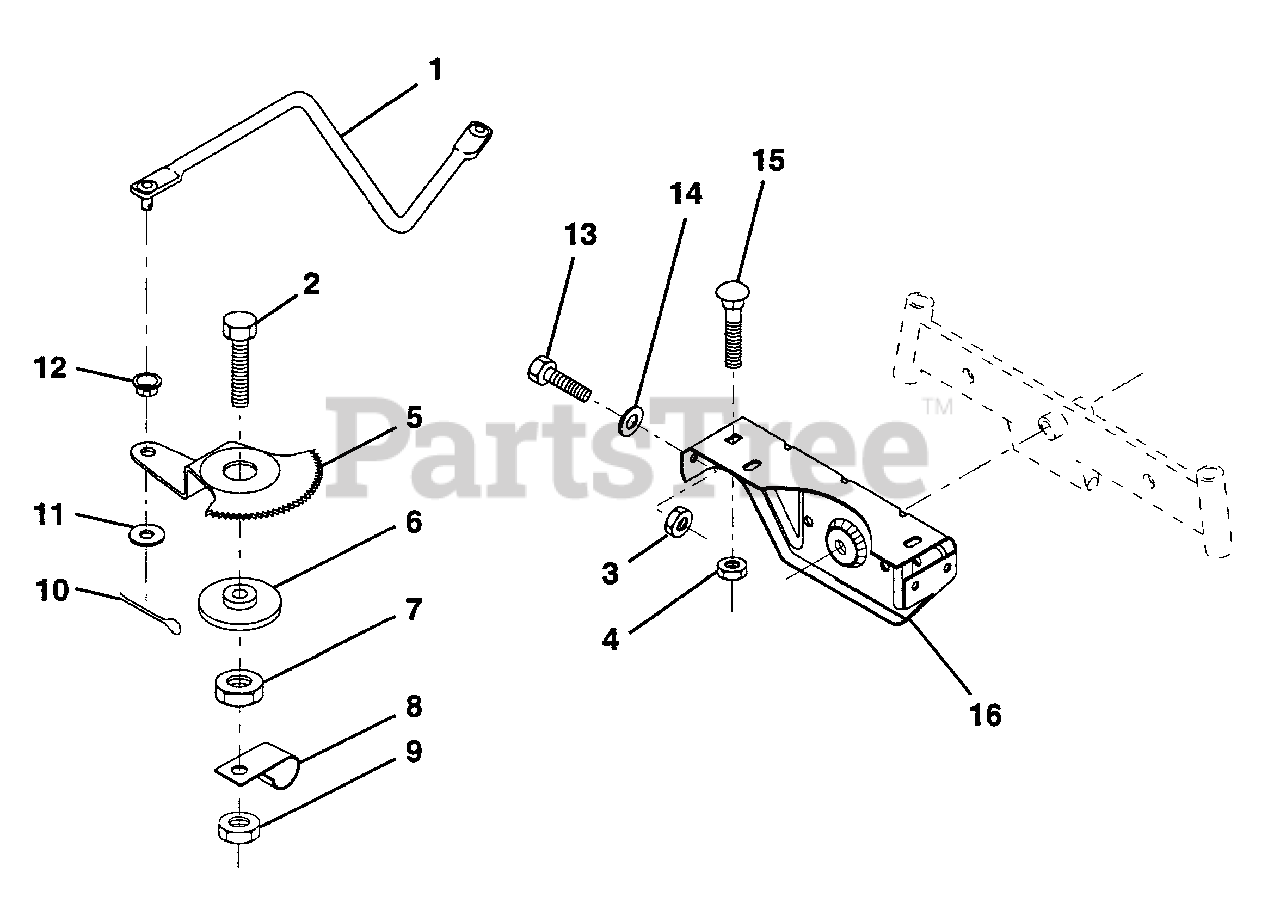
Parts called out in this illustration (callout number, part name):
1	Link, Drag
2	Bolt, Hex, Fin. 1/2-13 x 1-3/4
3	Nut, Hex, Crownlock 5/16-18
4	Nut, Crownlock 3/8-16
5	Gear, Sector
7	Nut, Hvy Hex, Top Lock 1/2-13 UNC
8	Clip, Insulated
9	Nut, Crownlock 3/8-16
10	Pin, Cotter 1/8 x 3/4
11	Washer 13/32 x 13/16 x 16 Gauge
13	Bolt, Hex Head 5/16-18 UNC x 1
14	Washer 11/32 x 7/8 x 16 Gauge
15	Bolt, Carriage 3/8-16 UNC x 3/4
16	Support, Front Axle
